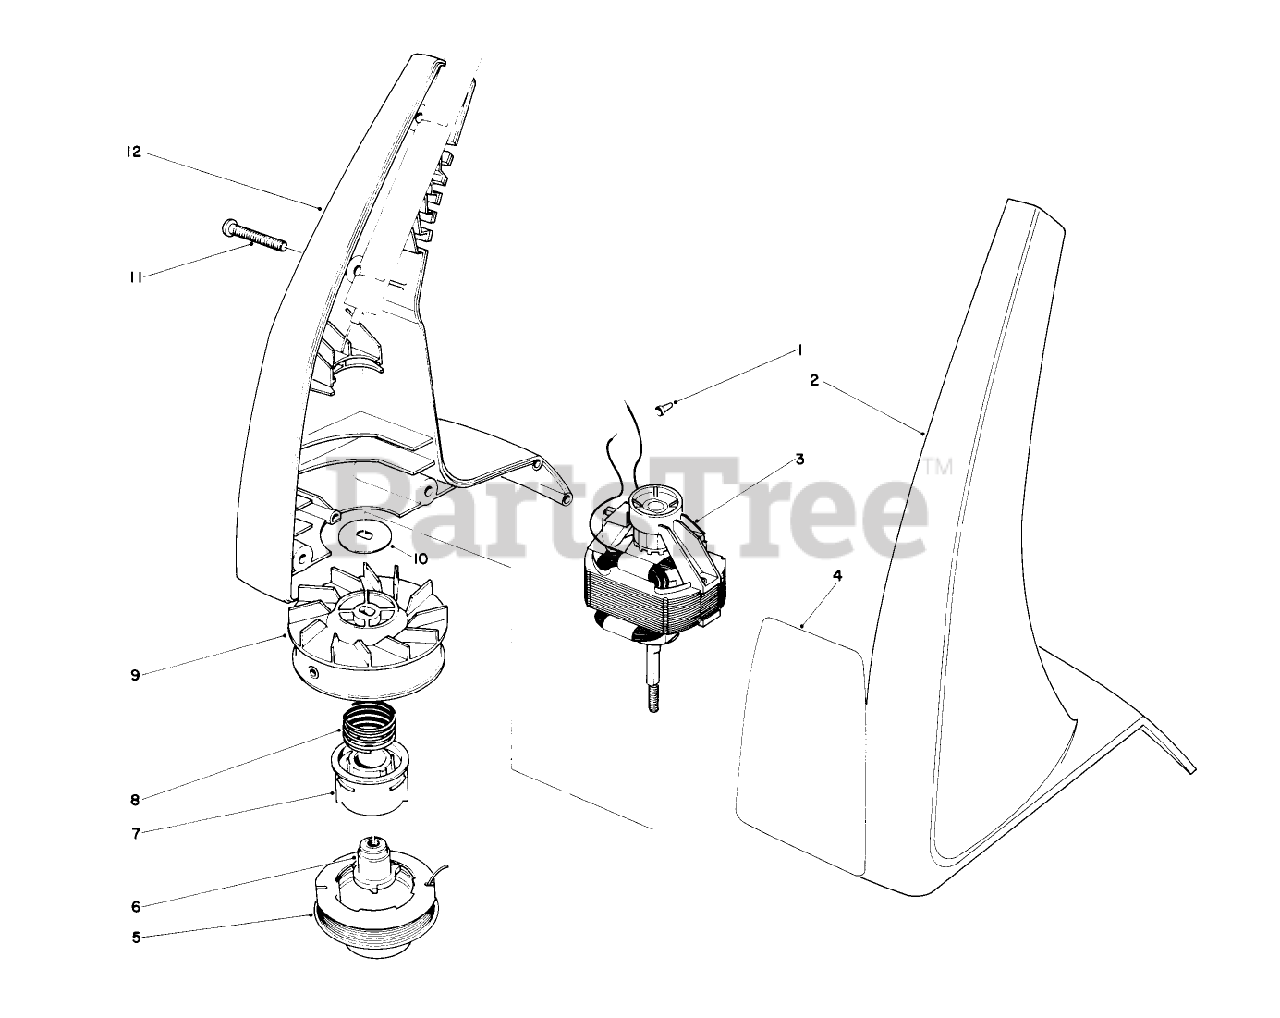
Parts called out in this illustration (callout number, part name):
1	CONNECTOR WIRE JOINT
2	L.H. HOUSING, 910
3	MOTOR, 910 TRIMMER
4	910 DECAL
5	Prewound Spool
6	DRIVER
7	CORE - SPOOL
8	Spring
9	Drum w/Eyelet
10	MOTOR WASHER
11	Screw
12	Housing-R.H.
